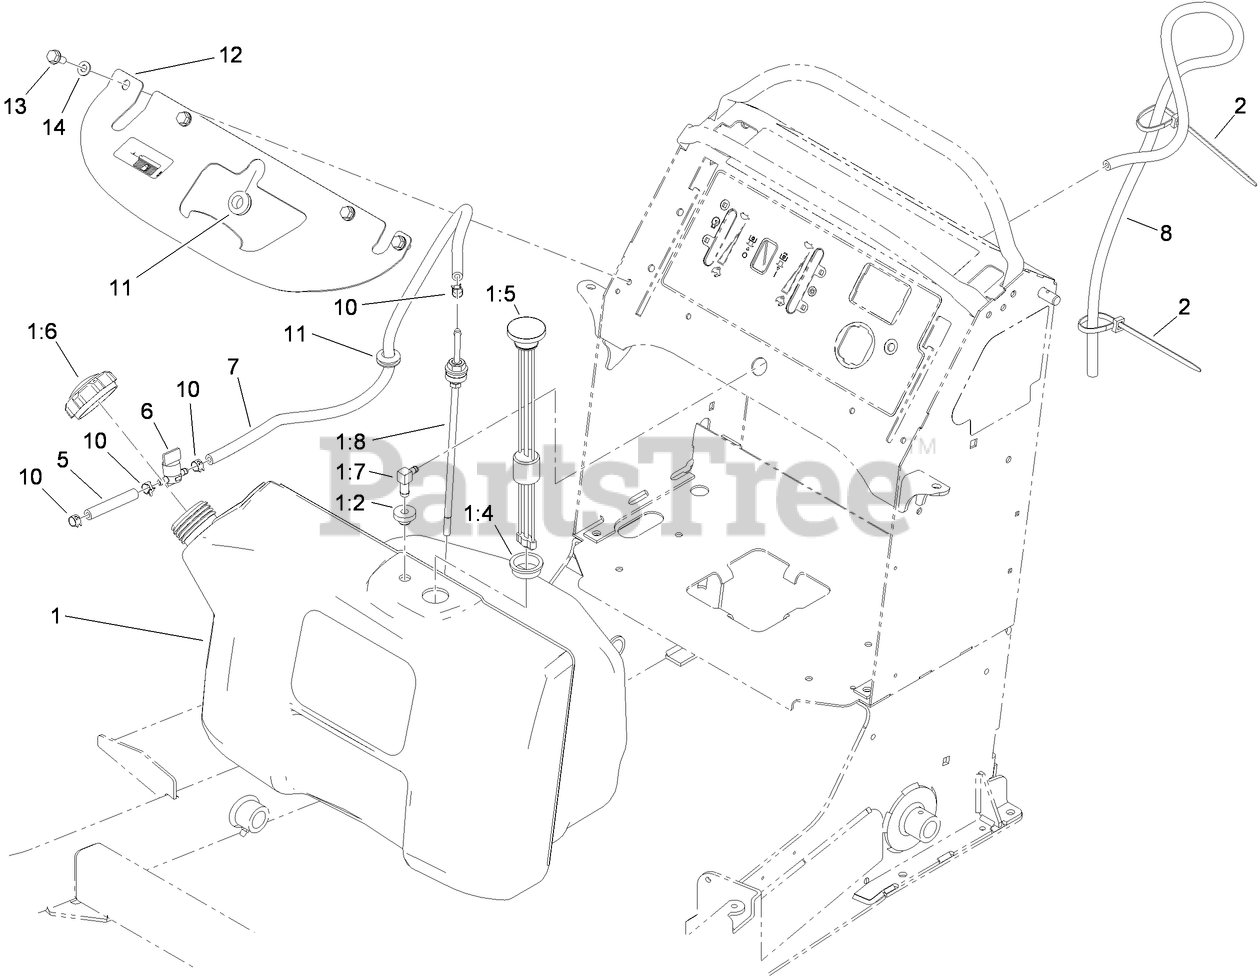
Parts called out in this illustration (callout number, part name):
1	TANK ASM
1:2	BUSHING
1:4	GROMMET
1:5	GUAGE-FUEL
1:6	CAP-FUEL
1:7	ELBOW-90 DEG
1:8	FITTING-FUEL, BULKHEAD
2	TIE-CABLE
5	HOSE-FUEL
6	VALVE-FUEL
7	HOSE-FUEL
8	HOSE-FUEL
10	CLAMP-HOSE
11	GROMMET
12	BRACKET-TANK
13	SCREW-HWHTF
14	WASHER-FLAT
